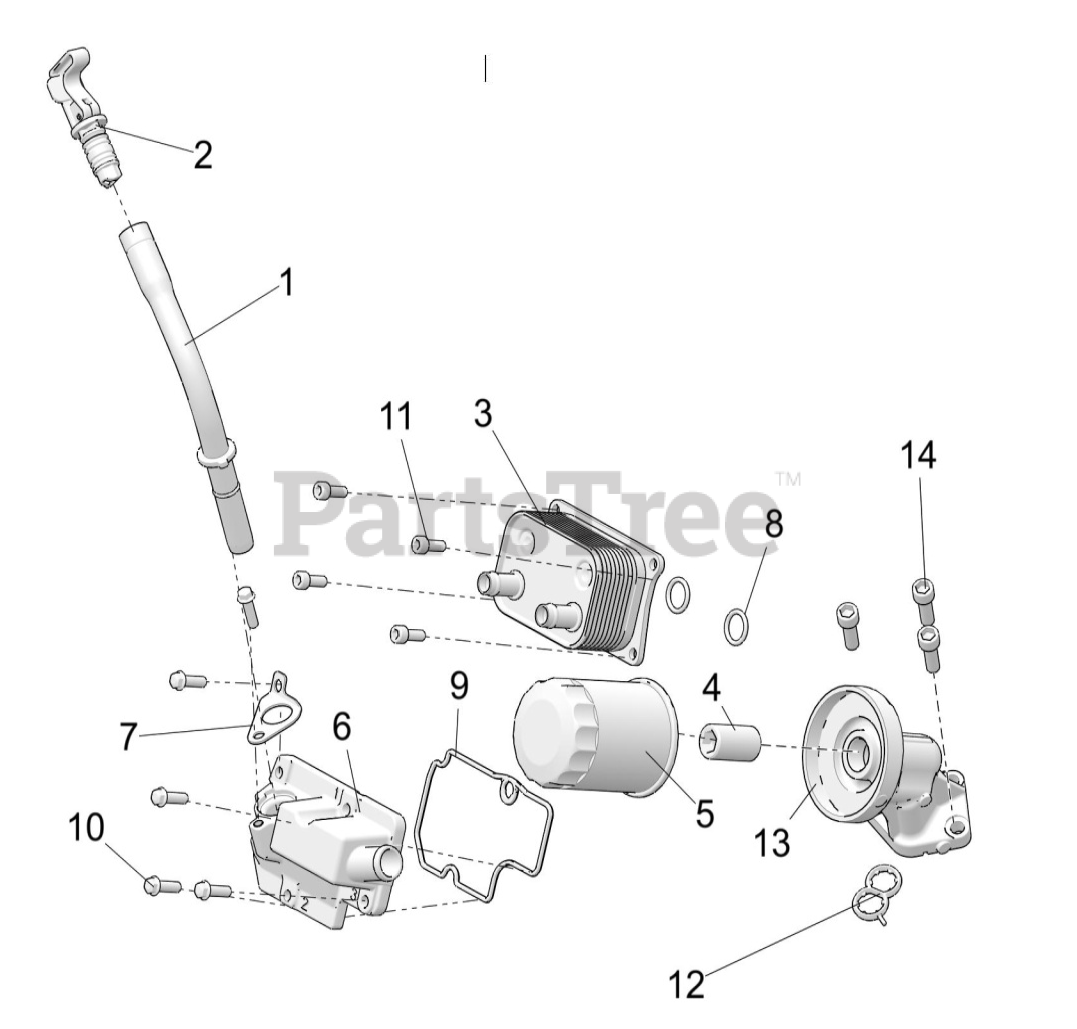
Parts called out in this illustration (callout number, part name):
1	ASM-OIL FILL TUBE
1	O-RING 12MMX2MM
2	ASM-DIPSTICK
3	COOLER-OIL TO WATER,5
4	ADAPTER-FILTER,STRAIGHT
5	FILTER-OIL,10 MICRON,(12)
6	COVER, BREATHER
7	BRACKET, TUBE, OIL FILL, LOWER
8	O-RING,.612X.818X.103
9	SEAL-COVER,BREATHER
10	SCR-M6X20,HXFLG,0600214
11	SCR-SH-M6X1.0X16 8.8 ZPY D204
12	SEAL-FILTER ADAPTER-3HOLE
13	ADAPTER-OIL FILTER,MACH
14	SCR-SH-M8X1.25X25 8.8 ZPC NYL
